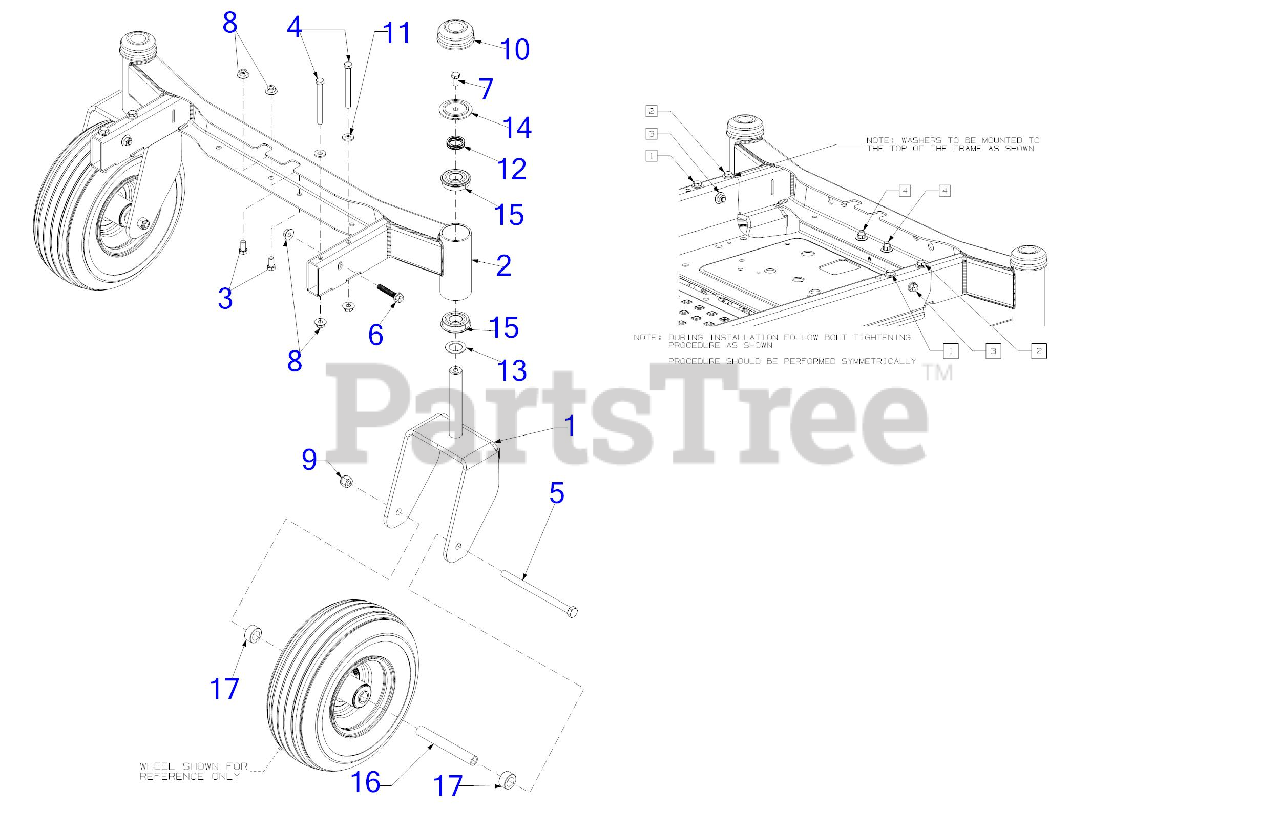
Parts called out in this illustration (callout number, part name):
3	HEX SCREW 3/8-16 x .75
4	SCREW 3/8-16 x 3.75 GR5
5	BOLT 1/2-20 x 7.25 GR5
6	SCREW 3/8-16 x 2.00 GR5
7	SCREW 3/8-16 x .75 GR 5
8	FLANGE LOCK NUT
9	HEX NUT CENTER
10	CASTER AXLE CAP
11	FLAT WASHER .385X.870X.090
12	WAVE WASHER
13	WASHER 1.010X1.560X.060
14	SHOULDER SPACER
15	BALL BEARING
16	CASTER SPACER
17	SPACER .76X1.23X.63
